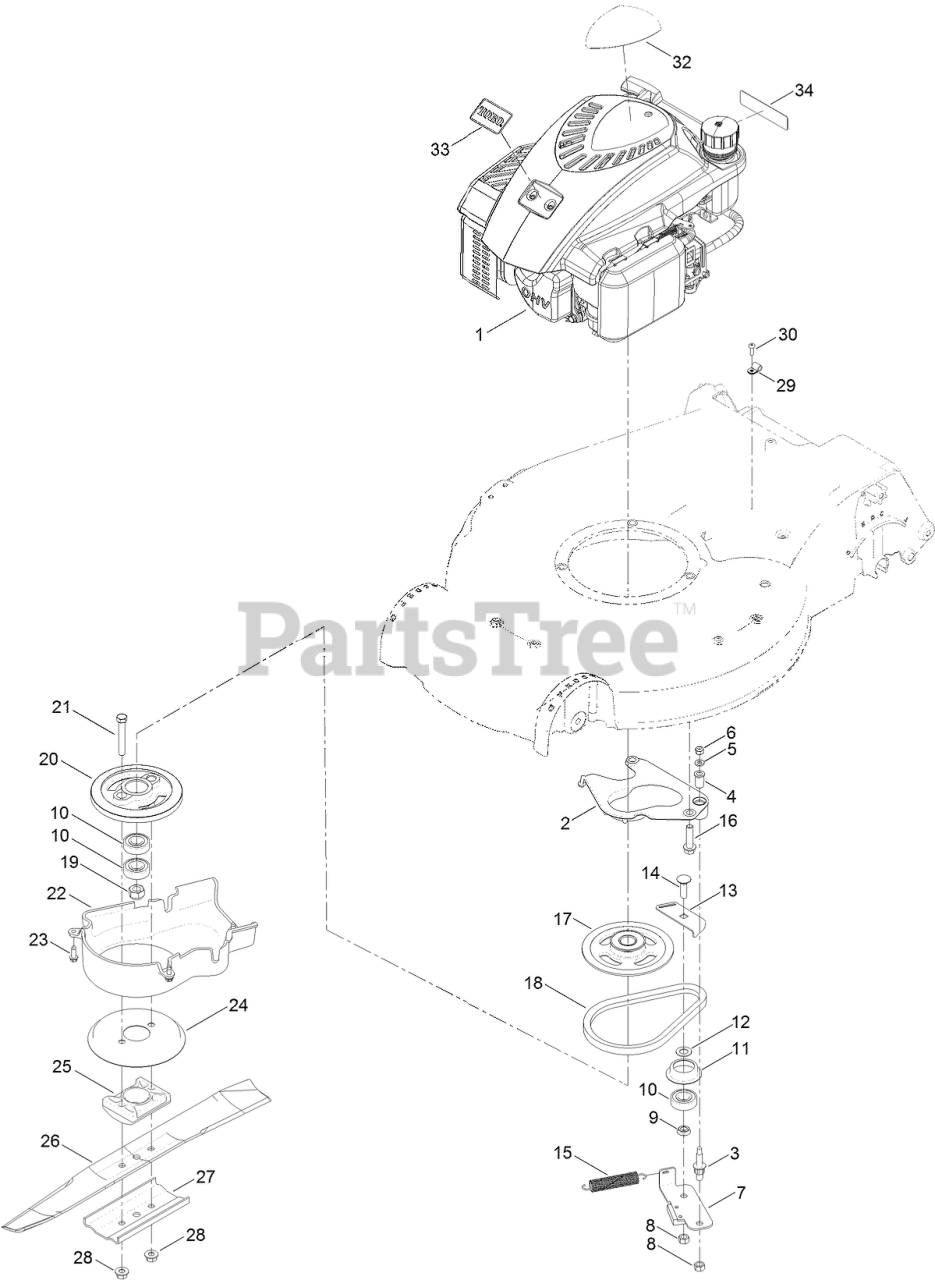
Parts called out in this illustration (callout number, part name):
1	ENGINE-1P65FC
2	PLATE-ANCHOR
3	BOLT-SHOULDER
4	BUSHING
5	WASHER-FLAT
6	NUT-LOCK, NI
7	PLATE-BRAKE
8	NUT-HEX
9	SPACER-BEARING
10	BEARING-BALL
11	RETAINER-BELT
12	WASHER-PLAIN
13	PLATE-GUIDE
14	BOLT-CARR
15	SPRING-TENSION, BRAKE
16	SCREW-HWH
17	PULLEY
18	BELT
19	NUT-HEX
20	DRUM
21	SCREW-HH
23	SCREW-HWHTF
24	DISC
25	SUPPORT-BLADE
26	BLADE-RECYCLING
27	SUPPORT-BLADE
28	NUT-FLANGE, LOCK
29	CLAMP
32	DECAL-SHROUD
34	DECAL-ARRESTER, SPARK
